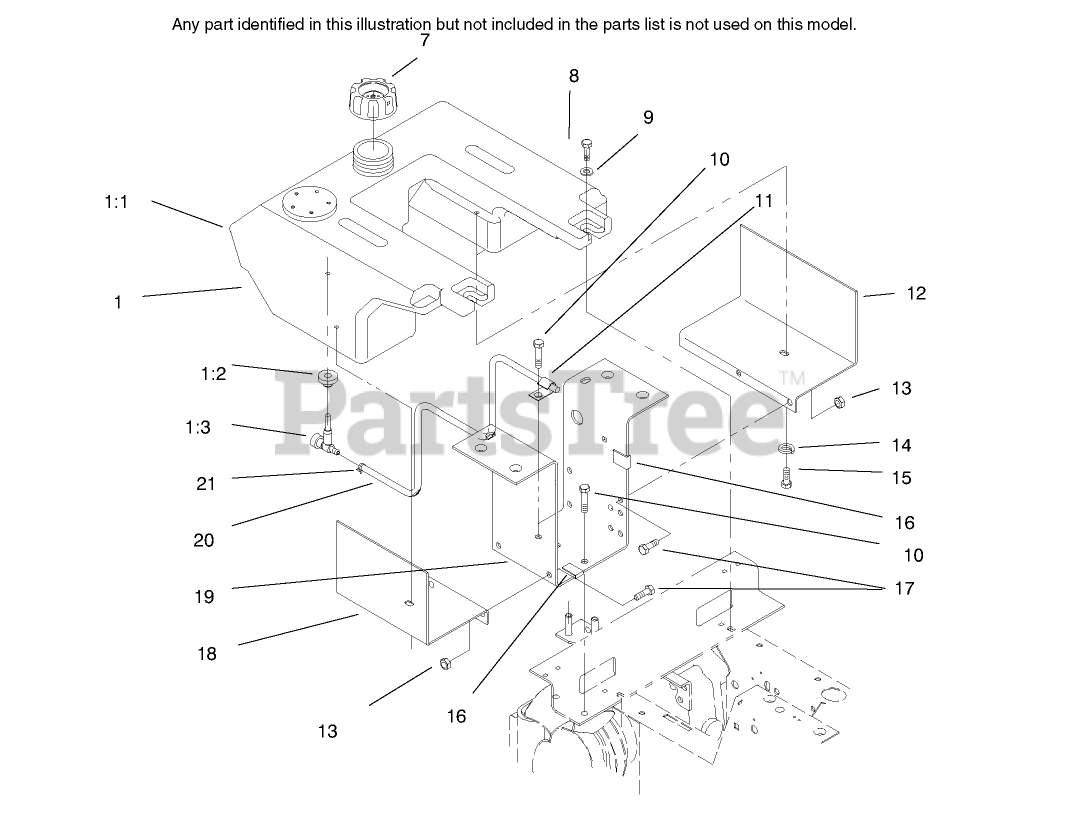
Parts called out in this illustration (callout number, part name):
1	TANK-FUEL
1:2	VALVE-FUEL
1:3	BUSHING
7	GAS CAP ASM
8	SCREW-HWHTF
9	WASHER-FLAT
10	SCREW-HH, LOCK
11	CLIP
12	Bracket-Support
13	NUT-LOCK, NI
14	WASHER-LOCK
15	SCREW-HH
16	CLIP-CABLE
17	SCREW-HH
18	Bracket-Support
19	Bracket-Fender Support
20	Line-Fuel 62"
21	CLAMP-HOSE
